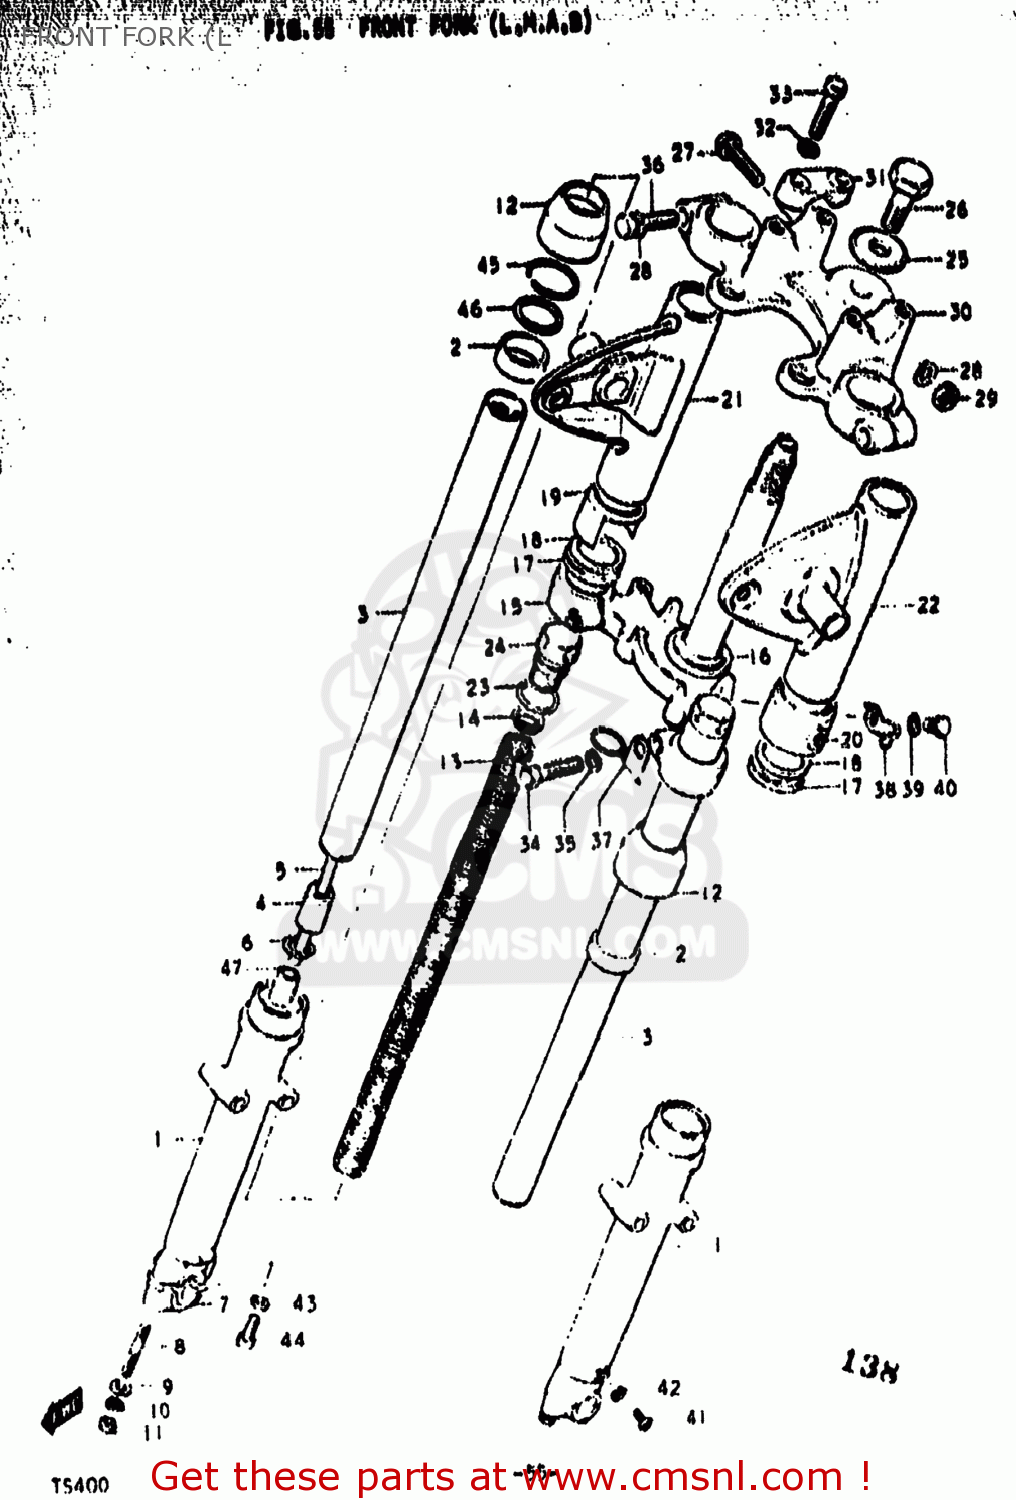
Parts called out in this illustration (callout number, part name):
0	DAMPER SET
1	TUBE,OUTER,RIGHT
2	SEAL,OIL
3	TUBE,FORK,INNER
4	PISTON L
5	CYLINDER,FRONT FORK
6	SNAP RING
7	HOLDER,AXLE
8	BOLT,STUD
9	WASHER
10	LOCK WASHER
11	NUT (8MM)
12	DUST SEAL,FRONT FORK
13	SPRING,FRONT FORK
14	SEAT,FRONT FORK SPRING
15	STEM,STEERING
16	RACE,STEERING OUTER LWR
17	GUIDE, COVER
18	CUSHION,HEADLAMP BRACKET
19	CUSHION,HEADLAMP BRACKET
21	BRACKET,HEADLAMP HOUSING
22	BRACKET,HEADLAMP,LEFT
23	O RING
24	CAP,FORK INNER TUBE
25	WASHER
26	BOLT,FORK INNER TUBE
27	BOLT,FORK INNER TUBE F
28	LOCK WASHER
29	NUT
30	HEAD,STEERING STEM
31	HOLDER,HANDLEBAR
32	LOCK WASHER
33	Bolt
34	BOLT,FR FORK LWR(12X33)
35	WASHER,LOCK 12
36	BOLT,FORK INNER TUBE F
37	CLIP
38	CLIP
39	LOCK WASHER
40	SCREW
41	SCREW
42	GASKET,DRAIN,PLUG (NAS)
43	GASKET (NAS)
44	BOLT,FORK CYLINDER(10X25)
45	RING,OIL SEAL STOPPER
46	WASHER, OIL SEAL
47	PIECE,OIL LOCK
